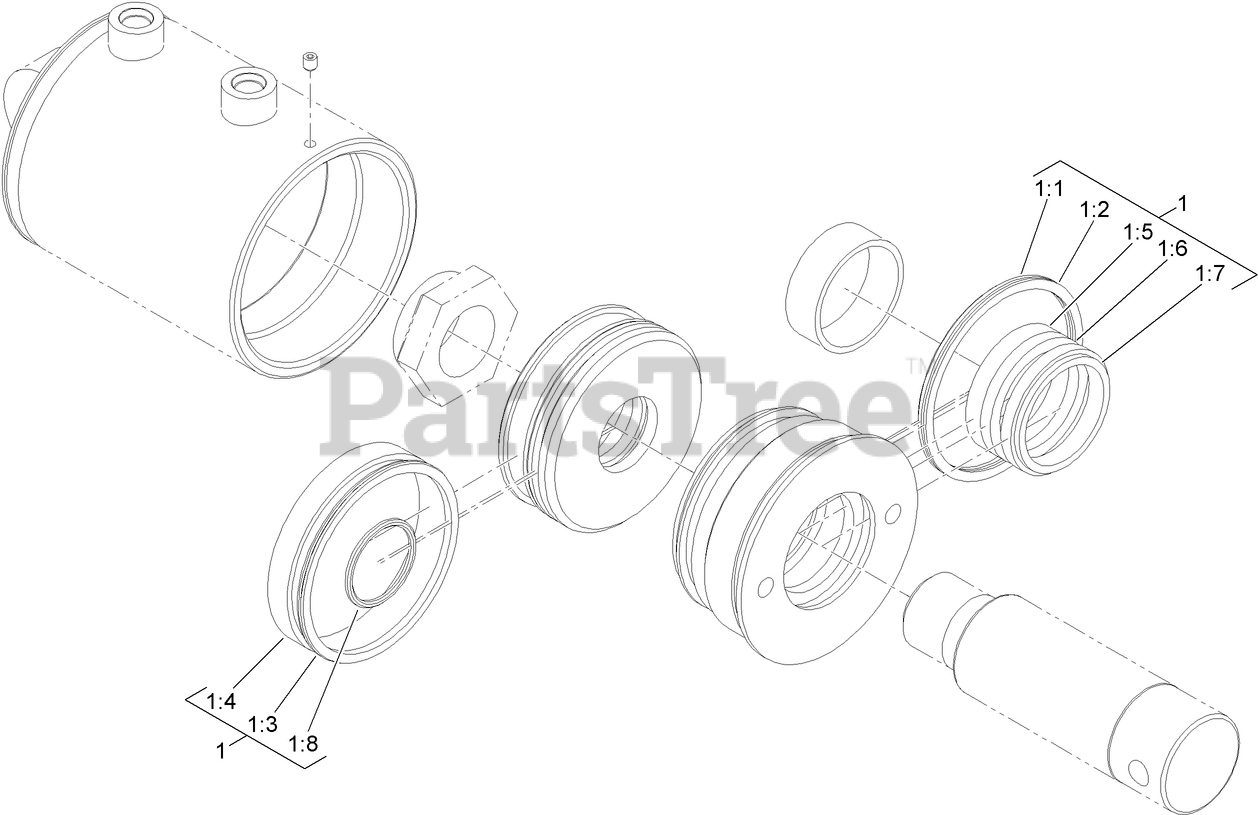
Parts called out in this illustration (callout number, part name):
1	SEAL KIT
1:1	O-RING
1:2	RING-BACKUP
1:3	SEAL-B P
1:4	RING-WEAR
1:5	SEAL-P P S
1:6	BEARING-MODULAR
1:7	DUST SEAL-HIGH TEMP
1:8	O-RING
